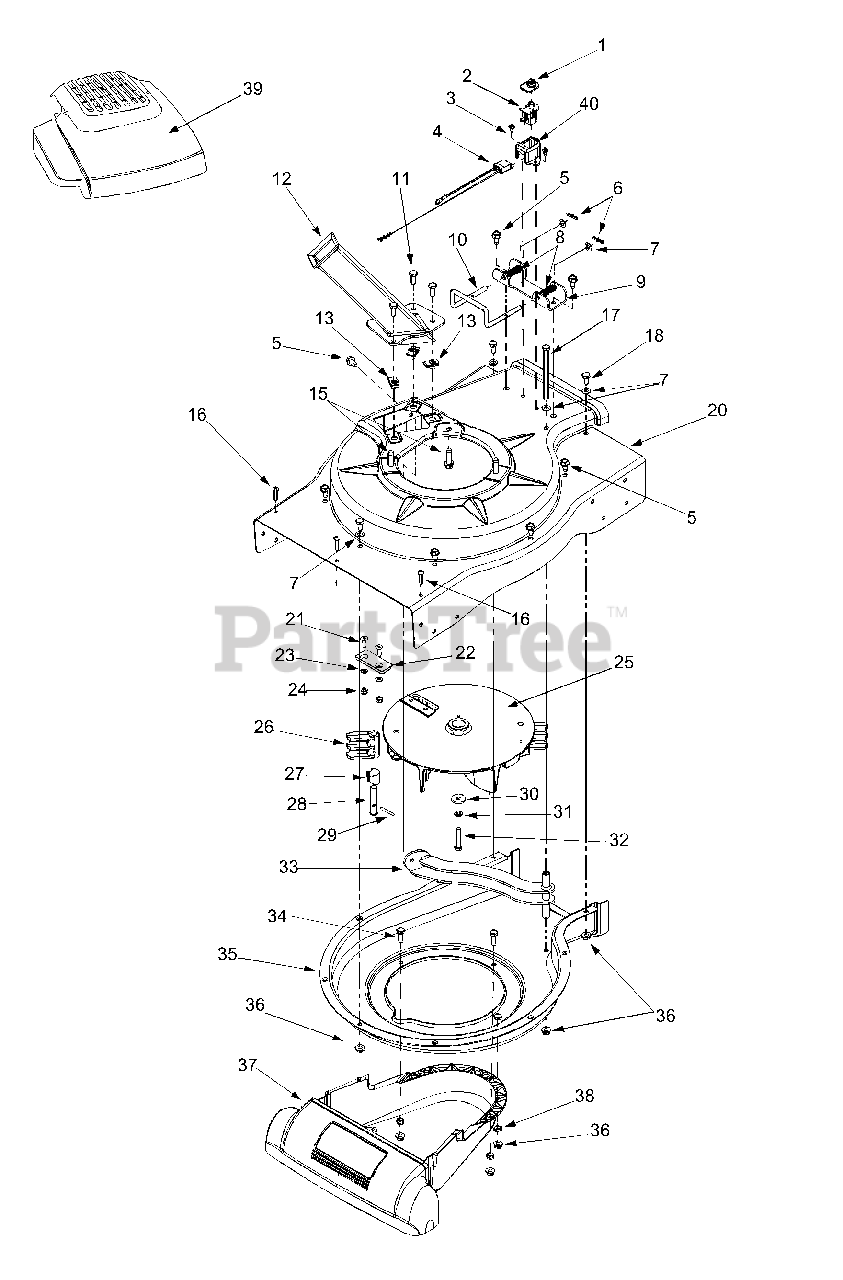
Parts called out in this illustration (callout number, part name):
1	Switch Cover
2	Safety Switch
3	Hex Washer Screw #10-16 x .50
4	Wire Harness
5	Hex Washer Screw 5/16-18 x .625
6	Cotter Pin
7	Flat Washer .330 ID x .630 OD
8	Compression Spring
10	Lock Rod
11	Hex Cap Screw 5/16-18 x .75
13	U-Clip Lock Nut 5/16-18
15	Hex Washer Screw 3/8-16 x 1.25
16	Screw #12-16 x 1.0
17	Hex Cap Screw 5/16-18 x 4.5
18	Hex Cap Screw 5/16-18 x .625
22	Chipper Blade
23	Lock Washer 5/16
24	Hex Lock Nut 5/16-24
25	Impeller Ass'y
26	Flail Blade
27	Pin Clip
28	Clevis Pin
29	Spiral Pin
30	Flat Washer 3/8 ID x 1.25 OD
31	Lock Washer 3/8
32	Hex Cap Screw 3/8-24 x 2.0
34	Hex Cap Screw 5/16-18 x .875
36	Lock Nut 5/16-18
37	Nozzle Cover
38	Lock Nut 5/16-18
39	Shroud
40	Safety Switch Cover
